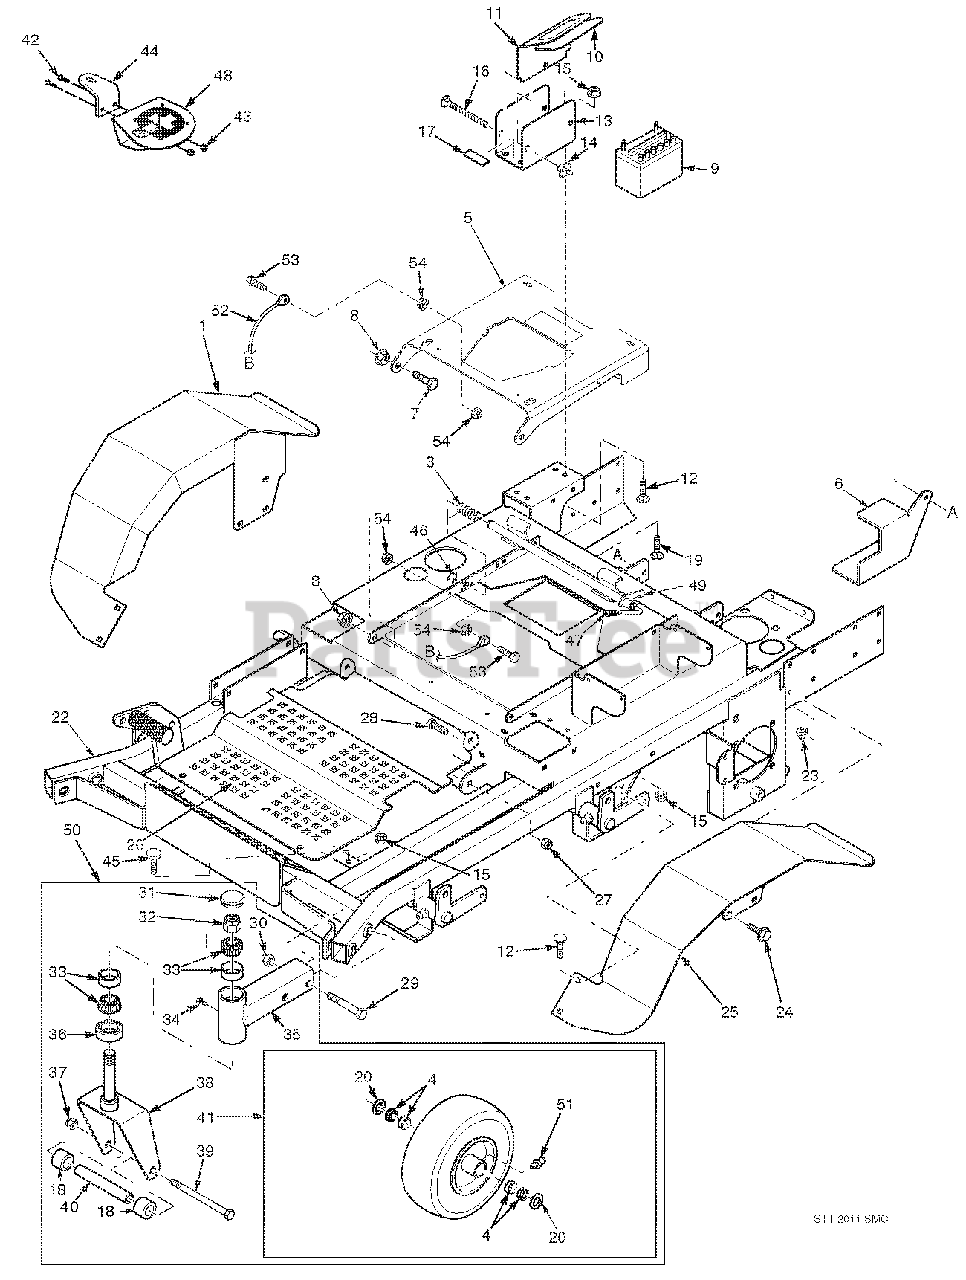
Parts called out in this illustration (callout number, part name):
1	Fender Weldment, RH
2	Bolt, Hex Head, 5/16-18 x 1, Zinc
3	Spring, Seat Latch
4	Bearing w/ Race
5	Seat Plate w/Decal
6	Guard, Fuel Line
7	Bolt, Hex Head 7/16-14 x 1-3/4"
8	Nut, 7/16-14 Serrated Flange
9	Battery
10	Pad, Battery Cover
11	Cover, Battery
12	Bolt, Carriage 5/16-18 x 3/4"
13	Plate, Battery Box
14	Wing Nut, 1/4-20 x 3/4"
15	Nut, Hex Serrated Flange 5/16-18
16	Bolt, Carriage 1/4-20 x 6"
17	Rubber Pad
18	Spacer, Caster Wheel
19	Bolt, Carriage 5/16-18 x 1"
21	Locknut, 3/8-16, Elast. Stop
22	Main Frame w/Decals
23	Nut, Hex Serrated Flange 3/8-16
24	Screw, Hex Serrated Flange 3/8-16 x 1"
25	Fender Weldment, LH
26	Foot Plate
27	Nut, Hex Elastic Stop 3/8-16
28	Bolt, Hex Head 3/8-16 x 1"
29	Bolt, Hex Head 5/8-11 x 4"
30	Nut, Hex Elastic Stop 5/8-11
31	Cap, Grease
32	Nut, Hex Elastic Stop 1.0-14
33	Bearing W/Race
34	Plug, 1/4-28 THD Form
35	Extention Weldment, Caster
36	Seal, 2.00" OD. x 1.625" Bore
37	Nut, Hex Elastic Stop 1/2-13
38	Yoke Weldment, Caster
39	Bolt, Hex Head 1/2-13 x 7-1/2"
39	Bolt, Hex Head 1/2-13 x 9-1/2"
40	Sleeve, Caster Wheel
41	Wheel Assy
42	Bolt, Hex Head 1/4-20 x 3/4"
43	Bolt, Hex Head 1/4-20 x 3/4"
44	Mounting Bracket, STT Cup Holder
45	Bumper, Rubber
46	Retaining Ring, .625" Ext. "E"
47	Grip, Seat Latch
48	Cup Holder Assembly
49	Lever Assembly, Seat Release
50	Caster Wheel Assembly
51	Grease Fitting
52	Cable, Seat Stop
53	Bolt, Hex Head 1/4-20 x 1-1/4"
54	Nut, Serrated Flange 1/4-20
